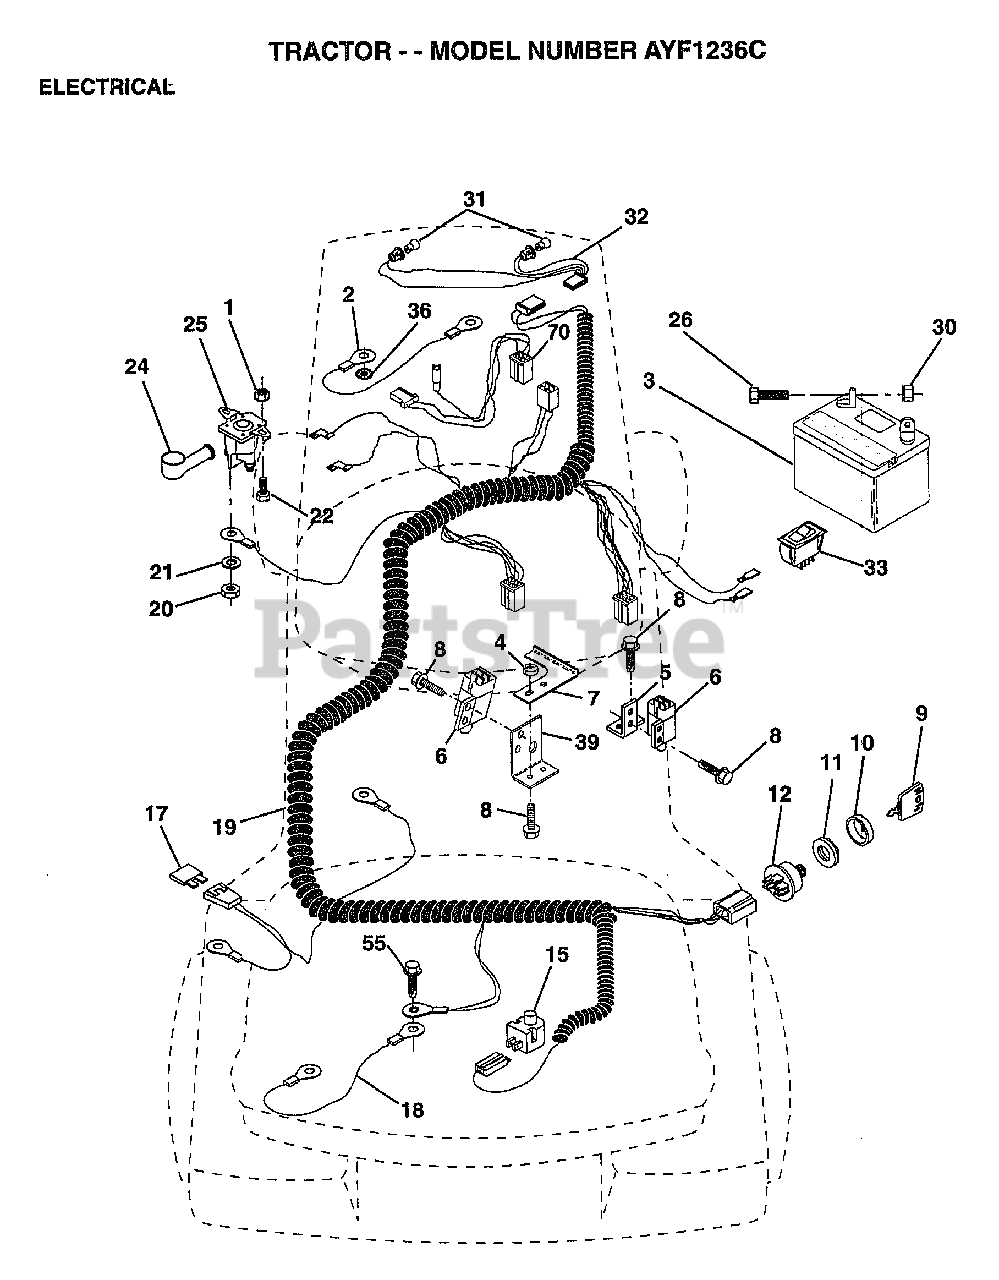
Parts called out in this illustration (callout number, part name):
1	NUT HXKEP 1/4X20
2	CABLE ASM.
4	LOCKNUT
5	BRACKET LT
6	SWITCH INTERLOCKT
7	KEEPER.ACTUAT.LR.
8	SCREW
9	KEY MLD GEN DELTA
10	COVER KEY SWITCH
12	SWITCH.IGNITION
15	SWITCH SEAT
17	FUSE HYT
18	CABLE ASSY
19	HARNESS.IGN.LR.
20	NUT
22	BOLT HXHD FIN
26	BOLT LT
30	NUT
31	HEADLAMP BULB
32	"HARNESS,LIGHT SOC"
33	SWITCH LT
36	LOCKWASHER
39	BRACKET SWT CLUTC
55	SCREW LT
70	HARNESS, ENGINE
